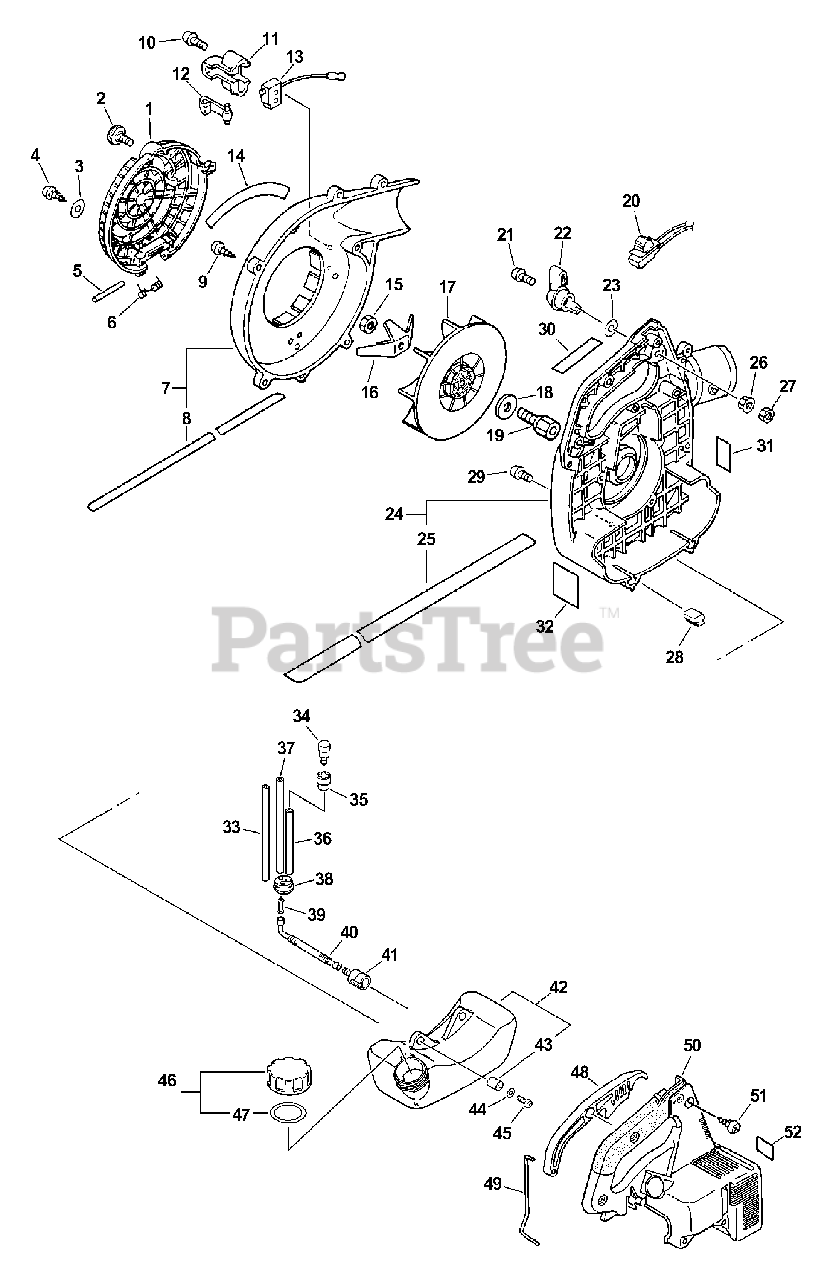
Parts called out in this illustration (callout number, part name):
1	COVER, INTAKE
2	THUMBSCREW
3	WASHER 5.5×12×0.8
4	SCREW 5×14
5	PIN, INTAKE COVER
6	SPRING, COIL
7	FAN COVER ASSY - LEFT
8	CUSHION
9	SCREW, TAPPING 5×20
10	SCREW 4×22
11	BRACKET, SWITCH
12	LEVER, SHUT OFF ACTUATOR
13	SWITCH, INTERLOCK
14	LABEL, MODEL
16	SHREDDER
19	HUB, FAN
20	IGNITION SWITCH ASSY
21	SCREW 5×25
22	CONTROL, THROTTLE
23	WASHER 5.5×12×0.8
24	FAN COVER ASSY - RIGHT
25	CUSHION
26	NUT, FLANGE M5
29	SCREW 4×22
30	LABEL, CAUTION
31	LABEL - CAUTION -- SPANISH
32	LABEL - CAUTION
33	PIPE, FUEL RETURN 3×6×90 MM CLEAR
34	VENT ASSY
35	HOLDER, VENT
36	PIPE, FUEL 3x-5x-70 BLACK
37	PIPE, FUEL 3×5×90 BLACK
38	GROMMET, FUEL
39	CONNECTOR, PIPE
40	PIPE, FUEL - CORRUGATED
41	FILTER, FUEL
42	TANK ASSY, FUEL
43	SPACER 6.2×7.8×6
44	WASHER 5.5×12×0.8
45	SCREW 5×16
46	CAP ASSY, FUEL
47	GASKET, FUEL CAP
48	CONTROL, THROTTLE
49	ROD, THROTTLE
50	SCREW, TAPPING 5×20
51	LABEL, CAUTION - HOT
52	COVER, ENGINE
